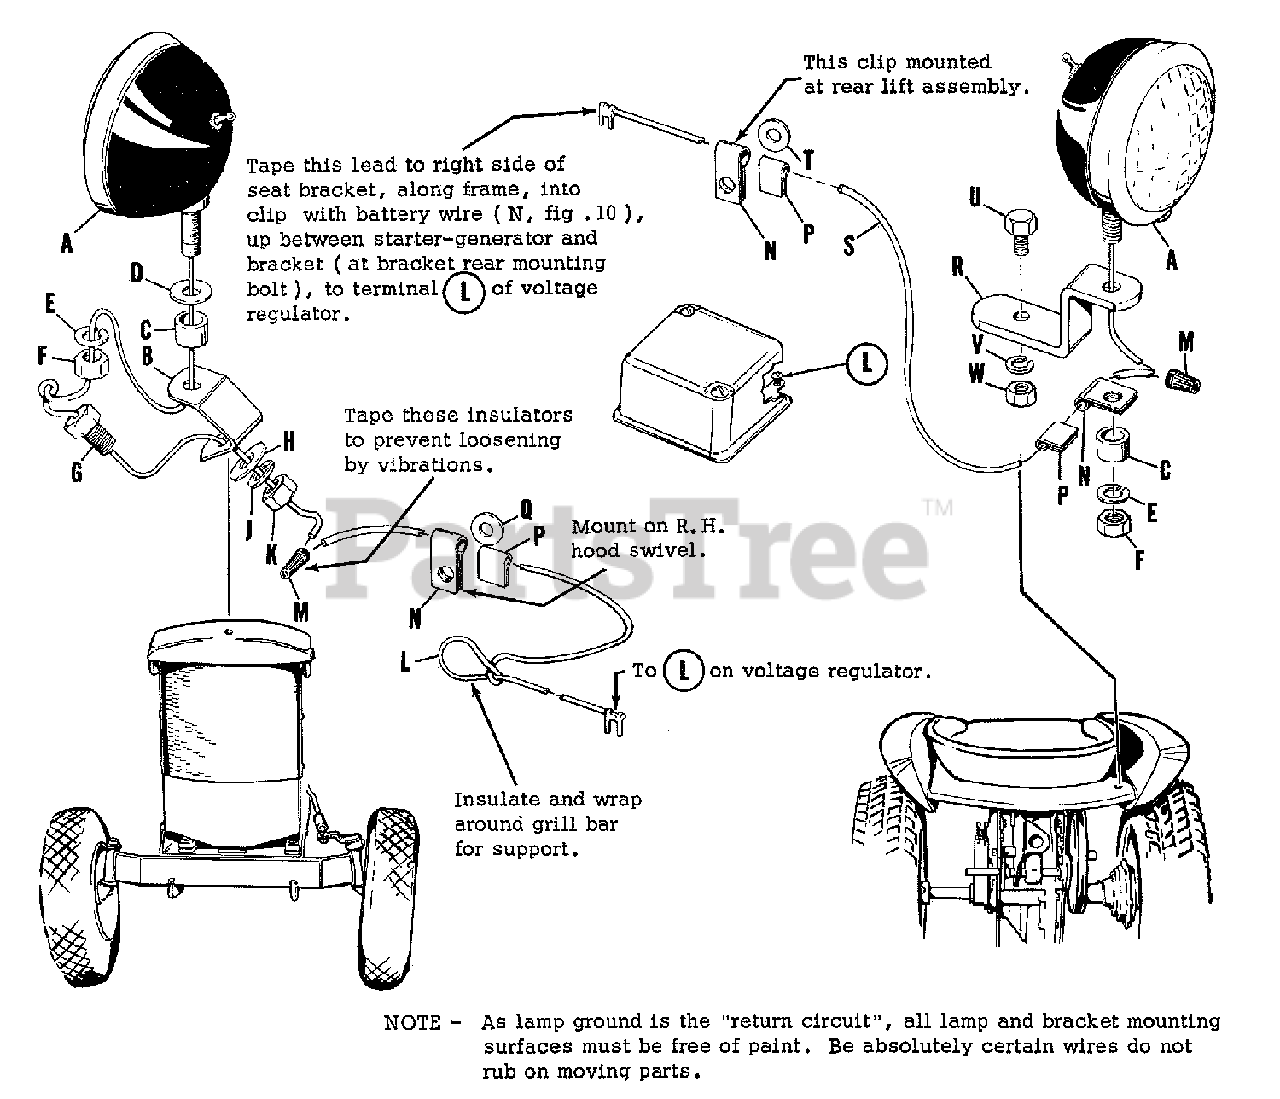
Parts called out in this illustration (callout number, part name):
A	LAMP ASSEMBLY, Tractor
B	BRACKET, Front Lamp
E	WASHER, Lock, 1/2"
F	NUT, Full, Hex, 1/2"-13 NC
G	SCREW, Cap, Hex
H	WASHER, Plain, 7/16"
J	WASHER, Lock, 7/16"
K	NUT, Full, Hex, 7/16-20 NF
L	WIRE, Regulator to Front Lamp
M	CONNECTOR, Wire
N	CLAMP, Wire
P	LINING, Clamp
Q	WASHER, Plain
R	BRACKET, Rear Lamp
S	WIRE, Regulator to Rear Lamp
T	WASHER, Plain, 3/8"
U	SCREW, Cap, Hex
V	WASHER, Lock
W	NUT, Hex, Full
